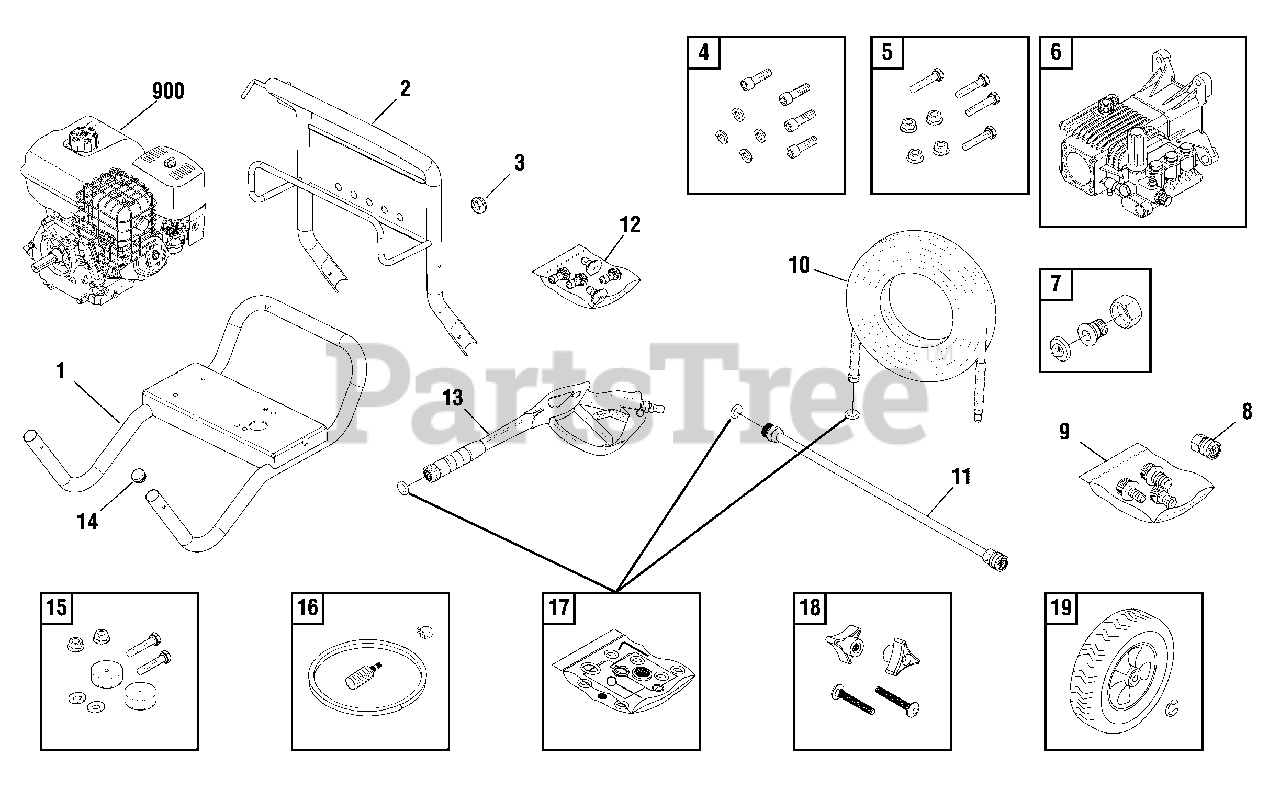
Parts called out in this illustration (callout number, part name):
4	KIT-HRDWR PUMP MOUNTING
5	KIT-HRDWR ENGINE MOUNTING
7	ADAPTER-GARDEN HOSE
8	QUICK CONNECT
9	KIT-GARDEN HOSE
12	KIT-QC NOZZLES
15	MOUNT-VIBRATION
18	KIT-HARDWARE HANDLE
900	* ENGINE
